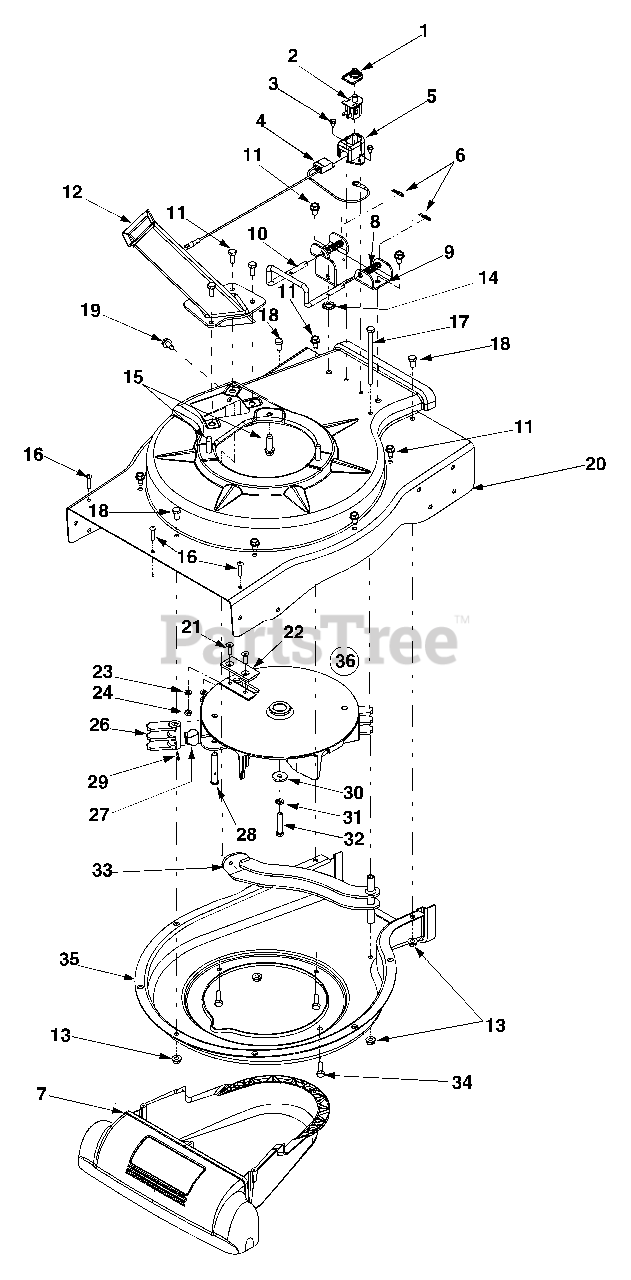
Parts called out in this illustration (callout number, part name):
1	Switch Cover
2	Safety Switch
3	Hex Washer Screw #10-16 x.50
4	Wire Harness
5	Safety Switch Cover
6	Cotter Pin
7	Nozzle
8	Compression Spring
10	Lock Rod
11	AB Screw 5/16-12 x.75
13	Flange Lock Nut, 5/16-18
14	External Lock Washer 5/16
15	Hex Screw, 3/8-16 x 1.25
16	Screw #12-16 x.750
17	Hex Cap Screw 5/16-18 x 4.5
18	Hex Cap Screw 5/16-18 x.625
19	Screw, 5/16-18 x.500
21	Hex Screw 5/16-24 x 1.0
22	Chipper Blade
23	Lock Washer 5/16
24	Hex Lock Nut 5/16-24
26	Flail
27	Pin Clip
28	Clevis Pin
29	Spiral Pin
30	Flat Washer.375 ID x 1.25 OD
31	Lock Washer 3/8
32	Hex Cap Screw 3/8-24 x 2.0
34	Shoulder Screw, #12-24
36	Impeller Assembly
